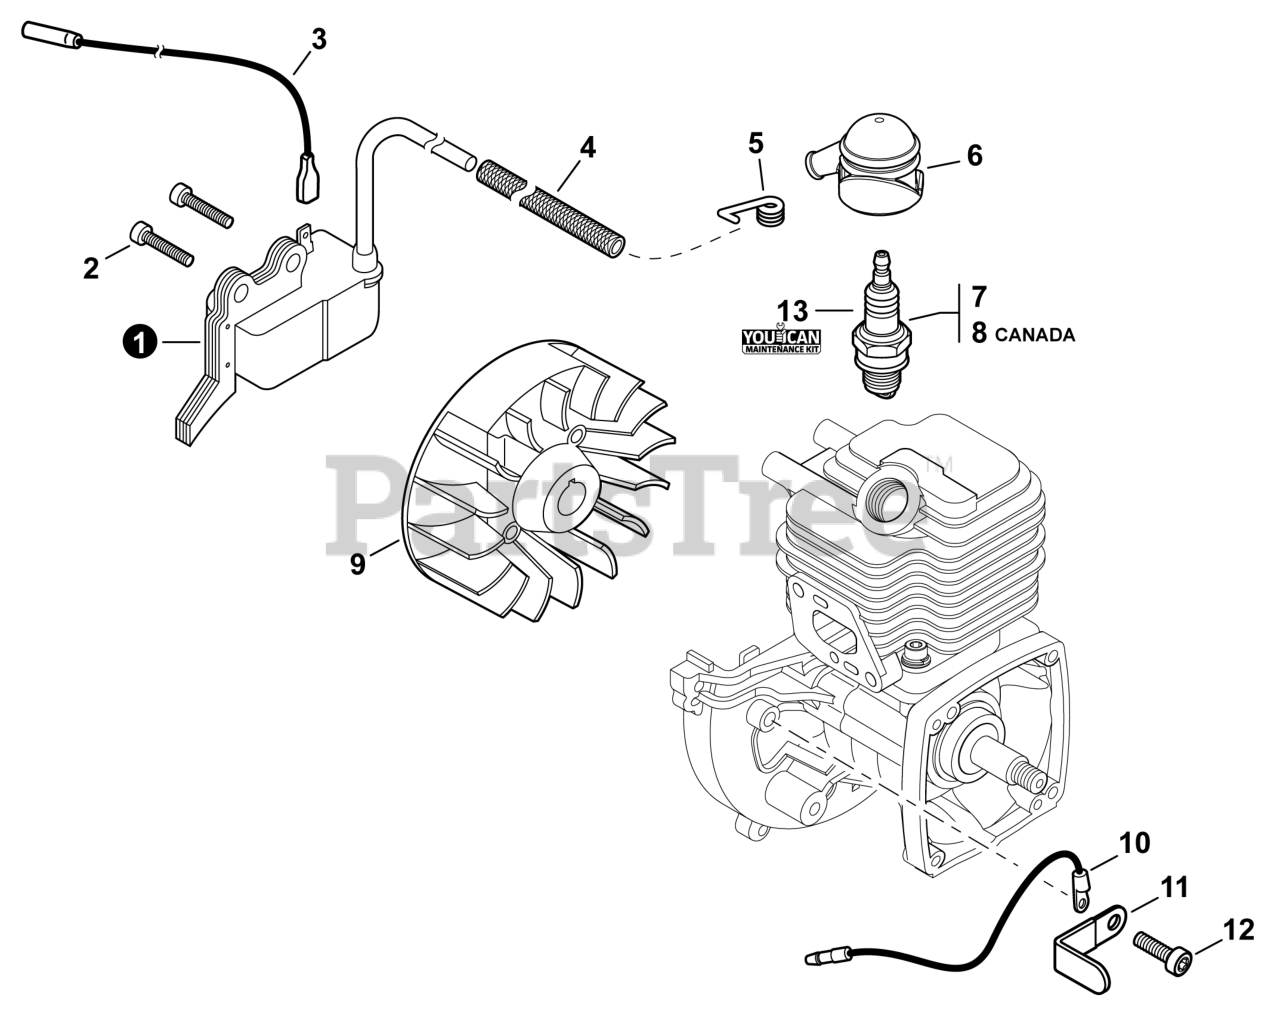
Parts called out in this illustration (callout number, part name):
1	COIL, IGNITION
2	BOLT, TORX 4x20
3	LEAD - IGNITION L= 210
4	TUBE, INSULATOR
5	TERMINAL, SPARK PLUG
6	CAP, SPARK PLUG
7	SPARK PLUG - BPM8Y
8	SPARK PLUG - BPMR8Y
9	FLYWHEEL
10	LEAD - GROUND
12	BOLT, TORX 5x10
13	TUNE-UP KIT - YOUCANT
